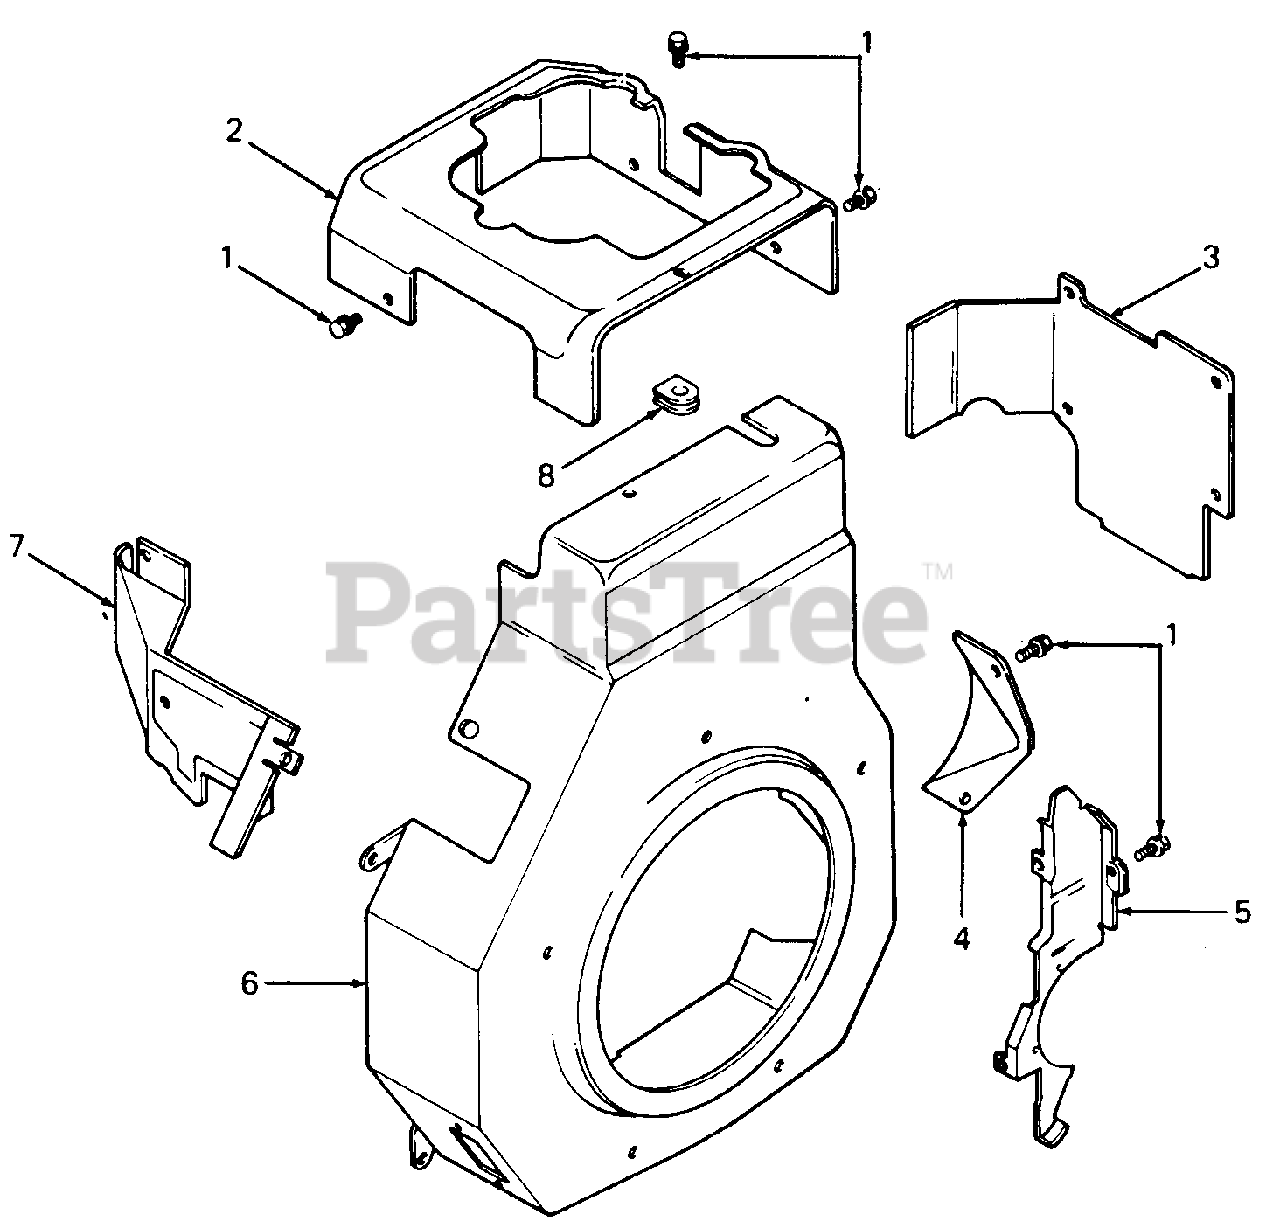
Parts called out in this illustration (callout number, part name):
1	Screw, Mounting, M5 X 0.8 X 10
2	Baffle, Cylinder Head
3	Baffler, Cylinder Barrel
4	Cover, Starter
5	Plate, Blower Housing
6	Housing, Blower
7	Baffle, Carburetor
8	Grommet, Blower Housing
